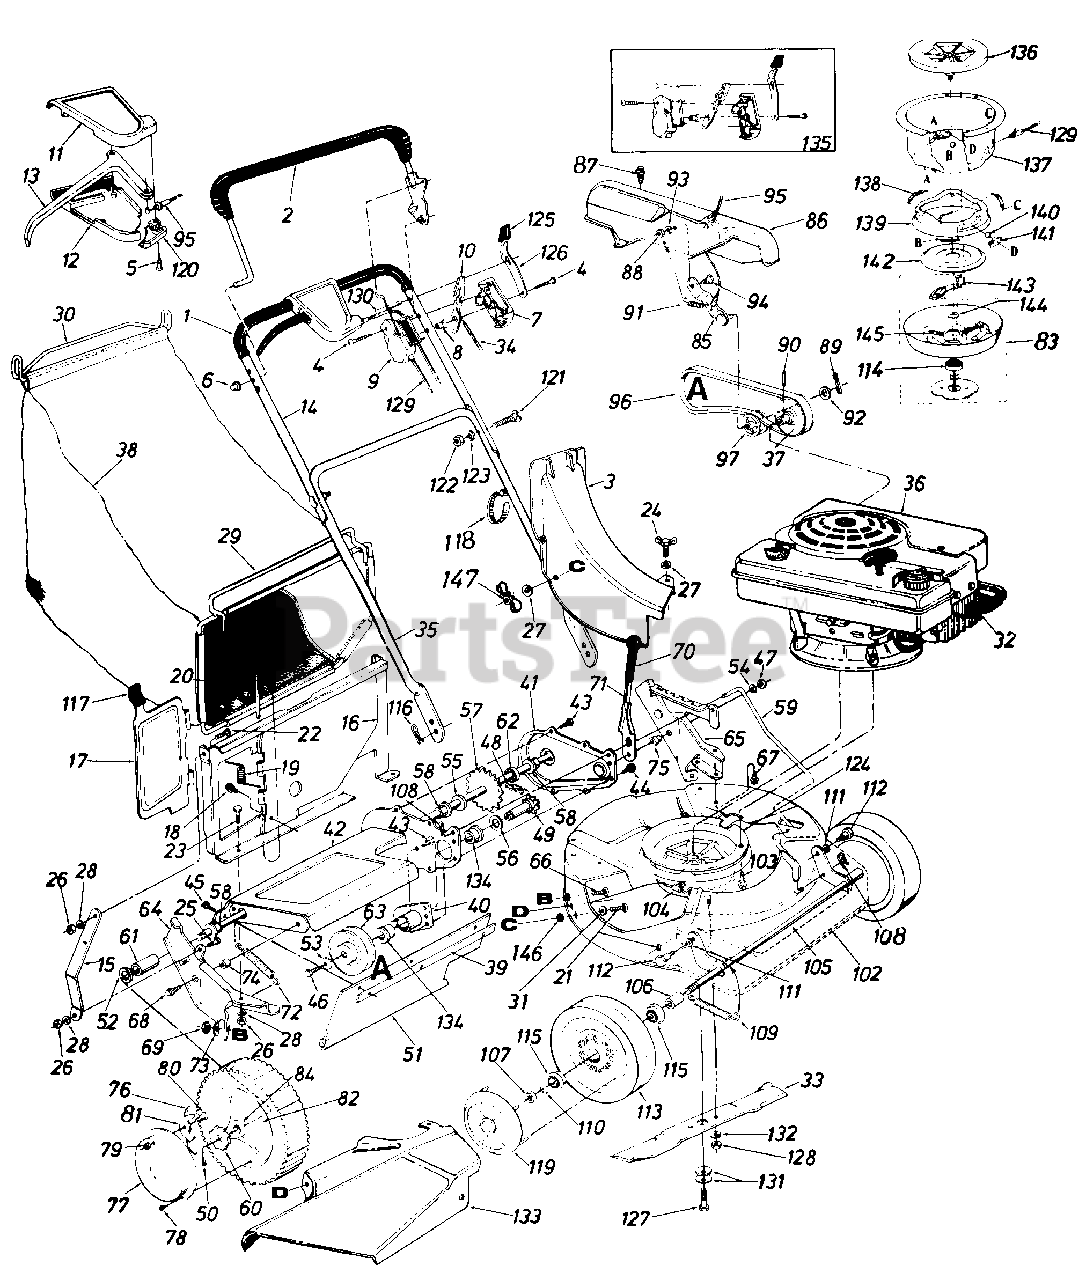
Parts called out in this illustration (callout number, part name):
2	Control Handle Ass'y. L.H.
3	Top Discharge Chute Ass'y.
4	Truss Mach. Scr. #12 x 1.50" Lg.
5	Fl-"C"-Sunk Hd. Tap Scr. #10 x .75" Lg.
6	Cap Speed Nut .31 Dia.
7	Control Panel Half
8	Control Disc Pin
9	Clutch Panel Half
10	Throttle Control Lever
11	Self-Propelled Control Cover
12	Self-Propelled Control Cover
13	Control Lever
14	Upper Handle Chrome
15	Panel Support Brk't.
16	Top Catcher Panel
17	Top Door
18	Hex "B" Tap Scr. #10 x .38" Lg.
19	Torsion Spring .20" I.D. x 1.14" Lg.
20	Pivot Pin .187" Dia. x 7.25" Lg.
21	Carriage Bolt 1/4-20 x .62" Lg.*
22	Truss Mach. Scr./ 1/2" x .50" Lg.
23	Hex Bolt 1/4-20 x .50" Lg.
24	Wing Bolt 1/4-20 x .62" Lg.
25	Truss Mach. Scr. 1/4-20 x .62" Lg.
26	Hex Nut 1/4-20 Thd.
27	Fl-Wash. .280" I.D. x .620" O.D.
28	L-Wash. 1/4" I.D.
29	Front Grass Catcher Frame
30	Grass Catcher Handle
31	Fl-Wash. .344 I.D. x .62 O.D.
32	Spark Plug Insulator
33	21" Blade
34	Throttle Control Wire 58.0" Lg.
35	Lower Handle Chrome
37	Engine Pulley 1/2"
38	21" Top Discharge Grass Bag
39	Retaining Strip
40	Bearing Hub Flange Ass'y.
41	Chain Cover
42	Chain Axle Ass'y.
43	Hex B-Tap Scr. 1/4" x .38"
44	Hex Wash. S-Tap Scr. 1/4-20 x .50" Lg.
45	Hex AB-Tap Scr. 1/4 x .62" Lg.
46	Hex Wash. TT-Tap Scr. 1/4-20
47	Hex Patch L-Nut 3/8-24 Thd.
48	#48 Chain .500" Pitch x .30 Links
49	Sprocket Shaft Ass'y.
50	Cotter Pin 118" Dia. x 1.00" Lg.
51	Rear Flap 3.75" x 17.30" Lg.
52	Fl-Wash. .531" I.D. x .930" O.D.
53	Bell-Wash. .265" I.D. x .75" O.D.
54	Fl-Wash. .385" I.D. x .87" O.D.
55	Fl-Wash. .510" I.D. x 1.0" O.D.
56	Fl-Wash. .62" I.D. x 1.12" O.D.
57	Rear Shaft Ass'y. 22.05" Lg.
58	Hex Flange Bearing .506" I.D. Plastic
59	Height Adj. Rod 1.50" x 19.42" Lg.
60	Ratchet Wheel 1.62" O.D.
61	Spacer.51" I.D. x .69" O.D. x .690" Lg.
62	Spacer.510" I.D. x 1.00" O.D. x .210" Lg.
63	1/2""V"-Pulley
64	R.H. Handle Wheel Brk't. Ass'y.
65	L.H. Handle Wheel Brk't. Ass'y.
66	Carriage Bolt 5/16-18 x .62" Lg.
67	Hex Wash. Hd. B-Tap Scr. 5/1 6-1 8
68	Hex Wash. Hd. TT-Tap Scr. 3/8-1 6
69	Hex Nut 5/16-18 Thd.
71	Height Adj. Lever 1.25 x 8.5" Lg.
72	Extension Spring .50" O.D. x 3.80" Lg.
73	Bell-Wash. .345" I.D. x .88" O.D.
74	Spacer.385" I.D. x .502" O.D. x .270" Lg.
75	Shld. Spacer.500" Dia. x .100
76	Spring Nylon
77	Hub Cap
78	Pan Hd. Tap Scr. #12 x .50" Lg.
79	Hex Ins. L-Nut 1/4-20 Thd.
80	Shld. Scr. .342" Dia. x .268
81	Pawl
82	Wheel Ass'y. Comp. Rear 8 x 1.75
83	Clutch Blade Housing Ass'y.
84	Flange Ball Bearing 1/2" I.D.
85	Belt Idler Bracket Ass'y.
86	Belt Cover
87	Hex Wash. S-Tap Scr. 1/4-20 x .50" Lg.
88	Hex Nut 1/4-20 Thd.
89	Cotter Pin 118" Dia. x 1.00" Lg.
90	Spring Pin Spir. 3116" Dia. x 1.00" Lg.
91	Extension Spring .33" O.D. x 1.12" Lg.
92	Fl-Wash. .531" I.D. x .9301/ O.D. x .050
93	L-Wash. 1/4" I.D.
94	Shld. Bolt .375" Dia. x .181
95	S.P. Cable x 53.0" Lg.
96	"V"-Belt 1/2" x 32.0" Lg.
97	Fl-ldler Plastic 1.62" Dia.
104	Speed Nut 1/4-20 U-Type
105	Front Axle Ass'y.
106	Sleeve .526" I.D. x .690" O.D. x .880" Lg.
107	Hex L-Nut 1/2-20 Thd.
108	Intern. Cotter Pin 5/16" Dia.
109	Extension Spring .50" O.D. x 3.20" Lg.
110	Fl-Wash. .531" I.D. x .930" O.D.
111	Intern. L-Wash. 3/8 x .56" O.D.
112	Shld. Bolt .623" Dia. x .425
113	Front-Wheel Ass'y. Comp. 7 x 1.75
114	Ball Brg. .669" I.D. x 1.574"
115	Flange Ball Bearing 1/2" I.D.
116	Intern. Cotter Pin 5/16" Dia.
117	Door Grip x 2.5
118	Cable Tie
119	Hub Cap Plastic
120	S.P. Control Cover
121	Curved Carr. Bolt 5/16-18 x 1.38" Lg.
122	Hex Nut 5/16-18 Thd.
123	L-Wash. 5/16" I.D.
124	Blade Brake Clutch Comp.
125	Spring Lever Knob
126	Lockout Spring
127	Hex Cent. L-Bolt 3/8-24 x 2.00" (Grade 8)
128	Hex Nut 3/8-24 Thd. (Grade 8)
129	BBC Clutch Cable x 46.0" Lg.
130	Lock Pin .3/4" Dia. x 1.75" Lg.
131	Bell-Wash. .400" I.D. x .88" O.D.
132	L-Wash. 3/8" I.D.
133	Side Chute Deflector
134	Flange Bushing
135	Kit Control Housing Comp.
136	Fan Adapter
137	Clutch Housing
138	Extension Spring .35" O.D. x 1.75" Lg.
139	Brake Cup Cone
140	Steel Ball .500" Dia.
141	Ball Block
142	Clutching Cone
143	Hex Tap L-Scr. 1/4-20 x .75" Lg.
144	Fl-Wash. .690" I.D. x 1.060" O.D.
145	Compression Spring .35" O.D. x 2.00" Lg.
146	Bolt Retainer 1/4 x .50 O.D.
147	Wing Nut
